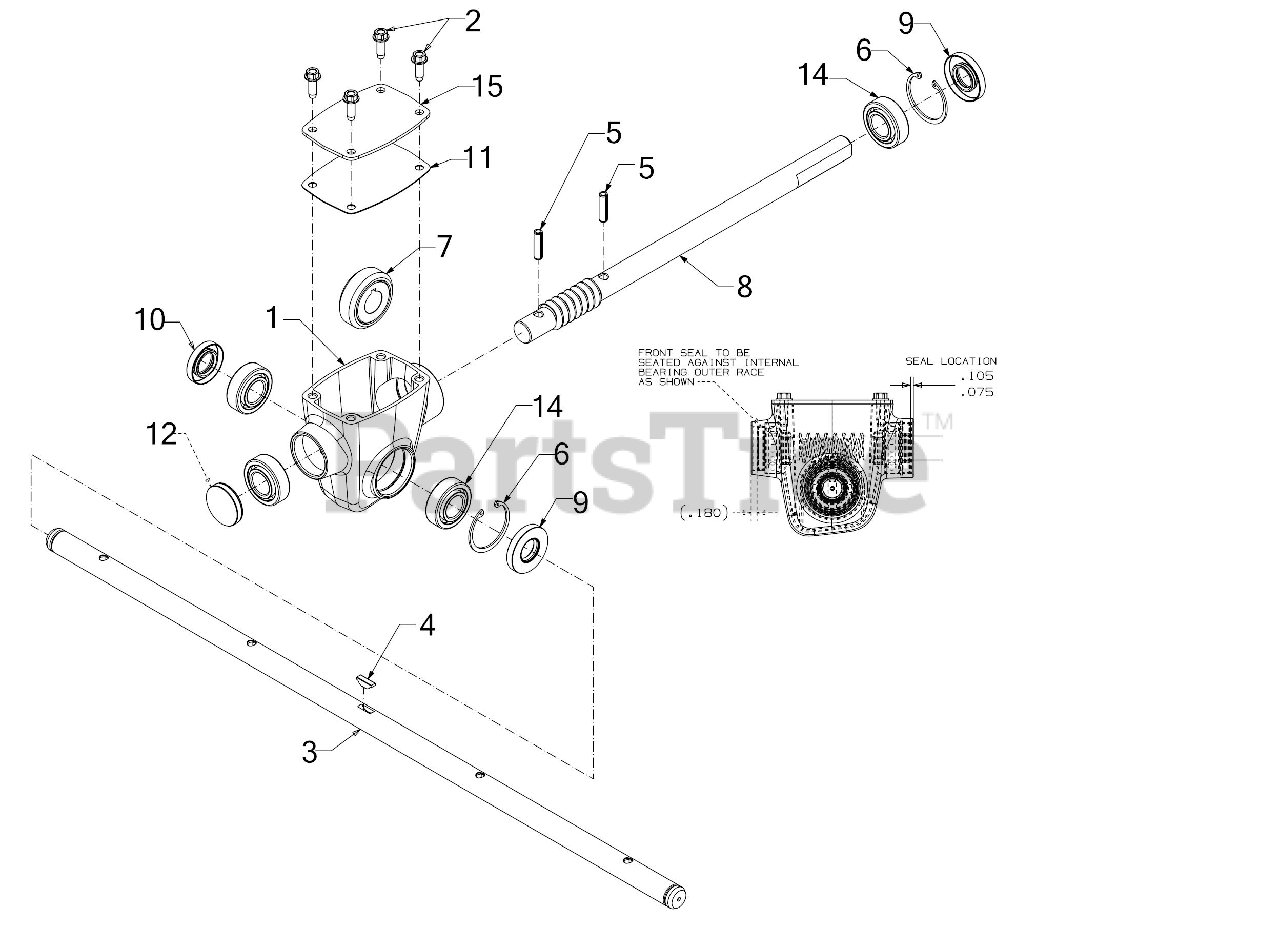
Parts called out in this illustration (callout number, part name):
1	AUGER GEARBOX HOUSING
2	SCREW 1/4-20 x .750
3	28" AUGER AXLE
4	KEY 3/16 x 5/8 H
7	WORM GEAR 20T
8	WORM SHAFT
11	GEARBOX COVER GASKET
12	GEARBOX PLUG
14	BALL BEARING
15	GEARBOX COVER
